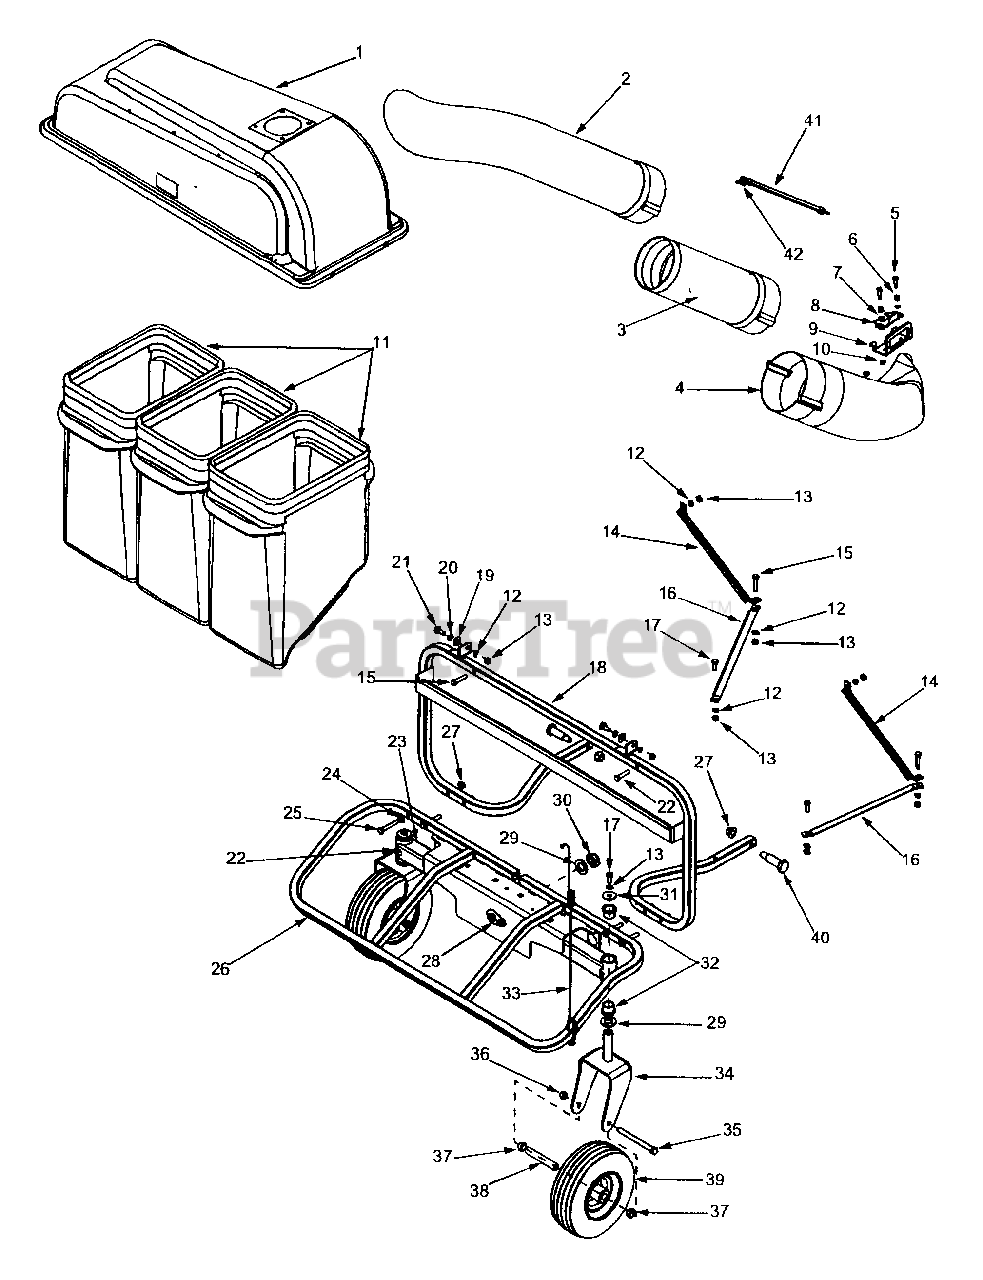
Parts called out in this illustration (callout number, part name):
1	Cover Assembly
2	Upper Tube Chute
3	Chute Extension
4	Discharge Chute
5	Shoulder Screw
6	Compression Spring .50 OD x.5 Lg.
7	Flat Washer
8	Bagger Latch
9	Chute Bracket
10	Lock Nut 5/16-18
11	Grass Bag Container
12	Lock Washer 3/8
13	Hex Nut 3/8-16
15	Hex Cap Screw 3/8-16 x 1.75
17	Hex Cap Screw 3/8-16 x 1.0
20	Flat Washer .510 ID x .750 OD
21	Shoulder Screw
22	Grease Fitting
23	Axle Assembly
24	Flat Washer .406 ID x .810 OD
25	Hex Cap Screw 3/8-16 x 2.5
28	Pivot Pin Assembly
30	Lock Nut
31	Flat Washer.390 ID x 1.5 OD
32	Flange Bearing
33	Cable Latch
35	Hex Cap Screw 1/2-20 x 5.50
36	Hex Lock Nut 1/2-20
37	Spacer .790 ID x .347 Lg.
38	Wheel Spacer
39	Wheel Assembly
40	Shoulder Bolt
41	Retainer Strap Assembly
42	Retainer Clip
